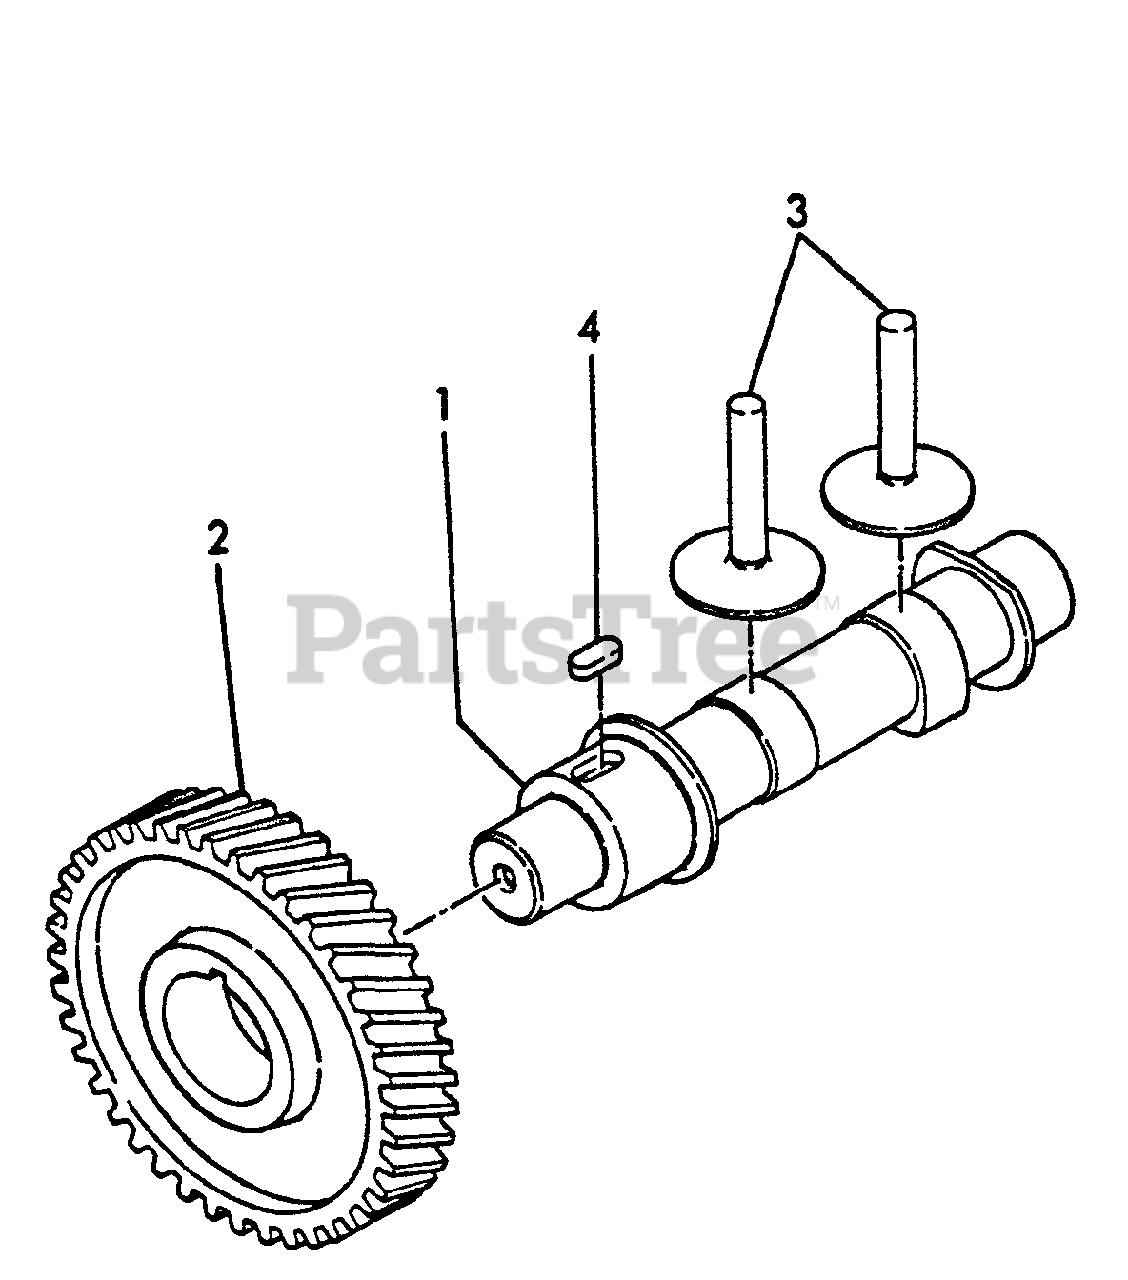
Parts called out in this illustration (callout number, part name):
1	CAMSHAFT
2	GEAR, CAMSHAFT
3	TAPPET
4	KEY - 5X5X12
